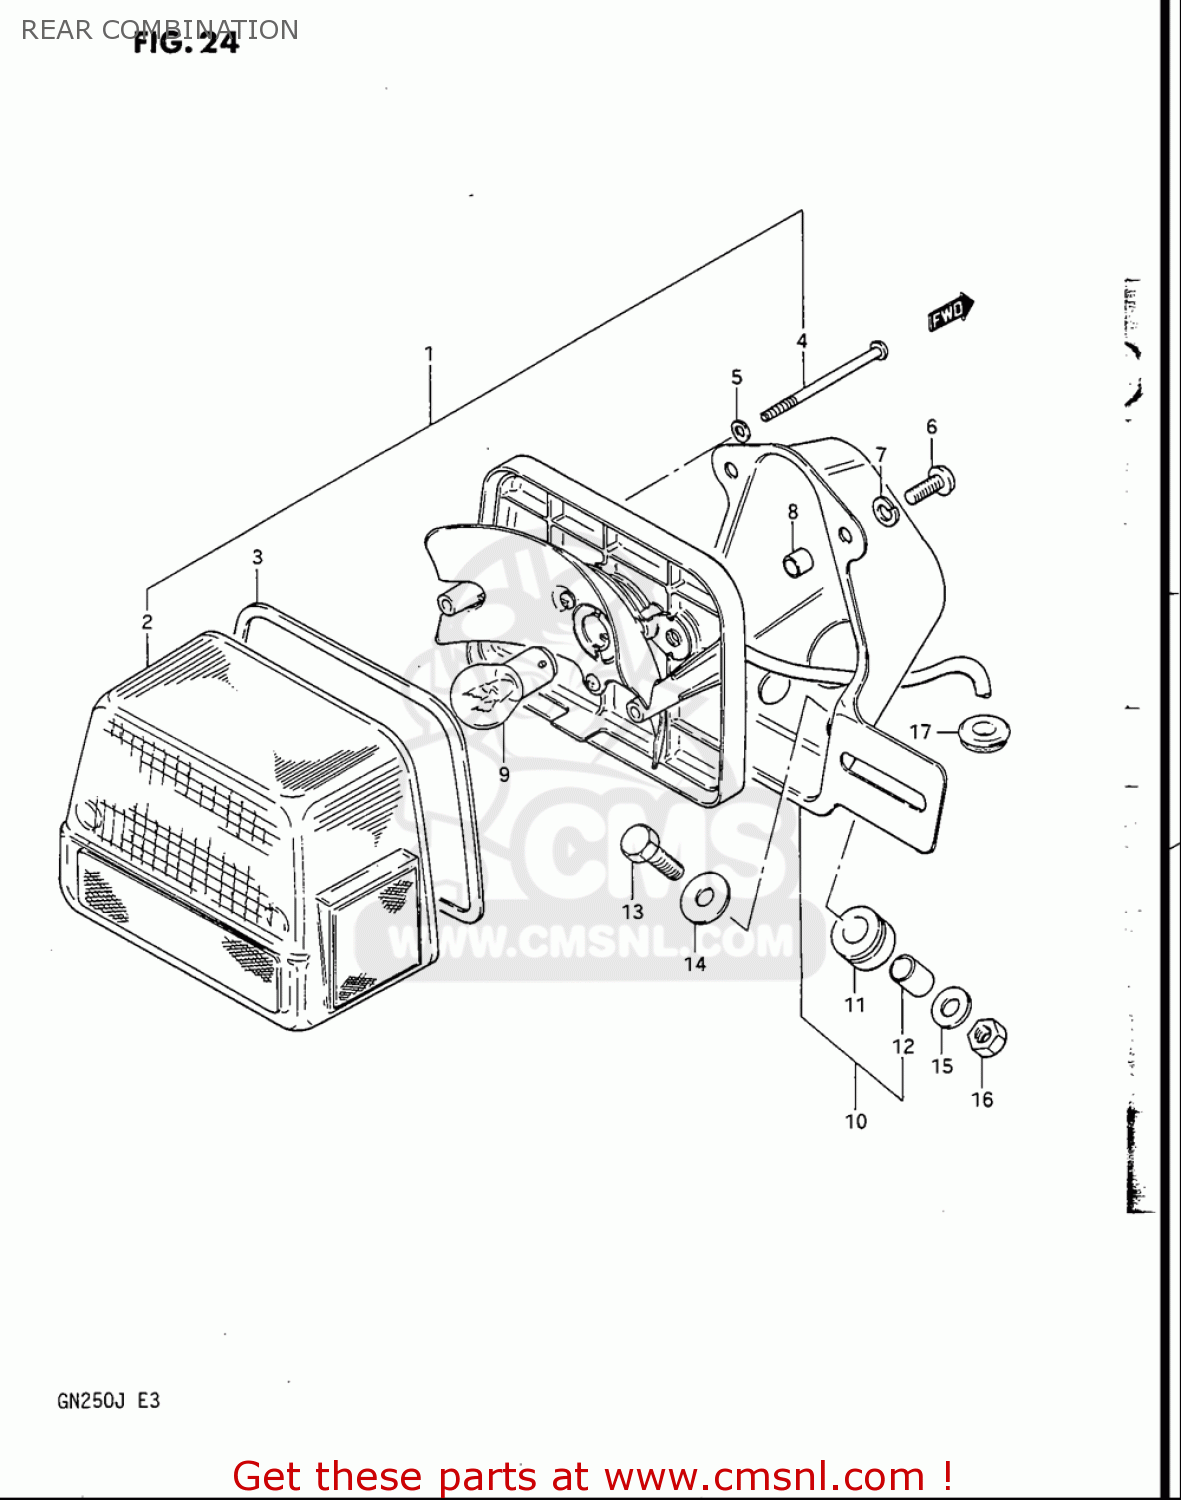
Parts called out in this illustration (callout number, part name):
1	LAMP UNIT,RR COMBNATION
2	LENS
3	GASKET (NAS)
4	SCREW
5	GASKET (NAS)
6	SCREW
7	WASHER,LOCK
9	BULB(12V23W)
10	BRACKET UNIT,TAIL LAMP
11	CUSHION
12	SPACER
13	BOLT
14	WASHER(6.5X20X1.2)
15	WASHER
16	NUT
17	GROMMET
